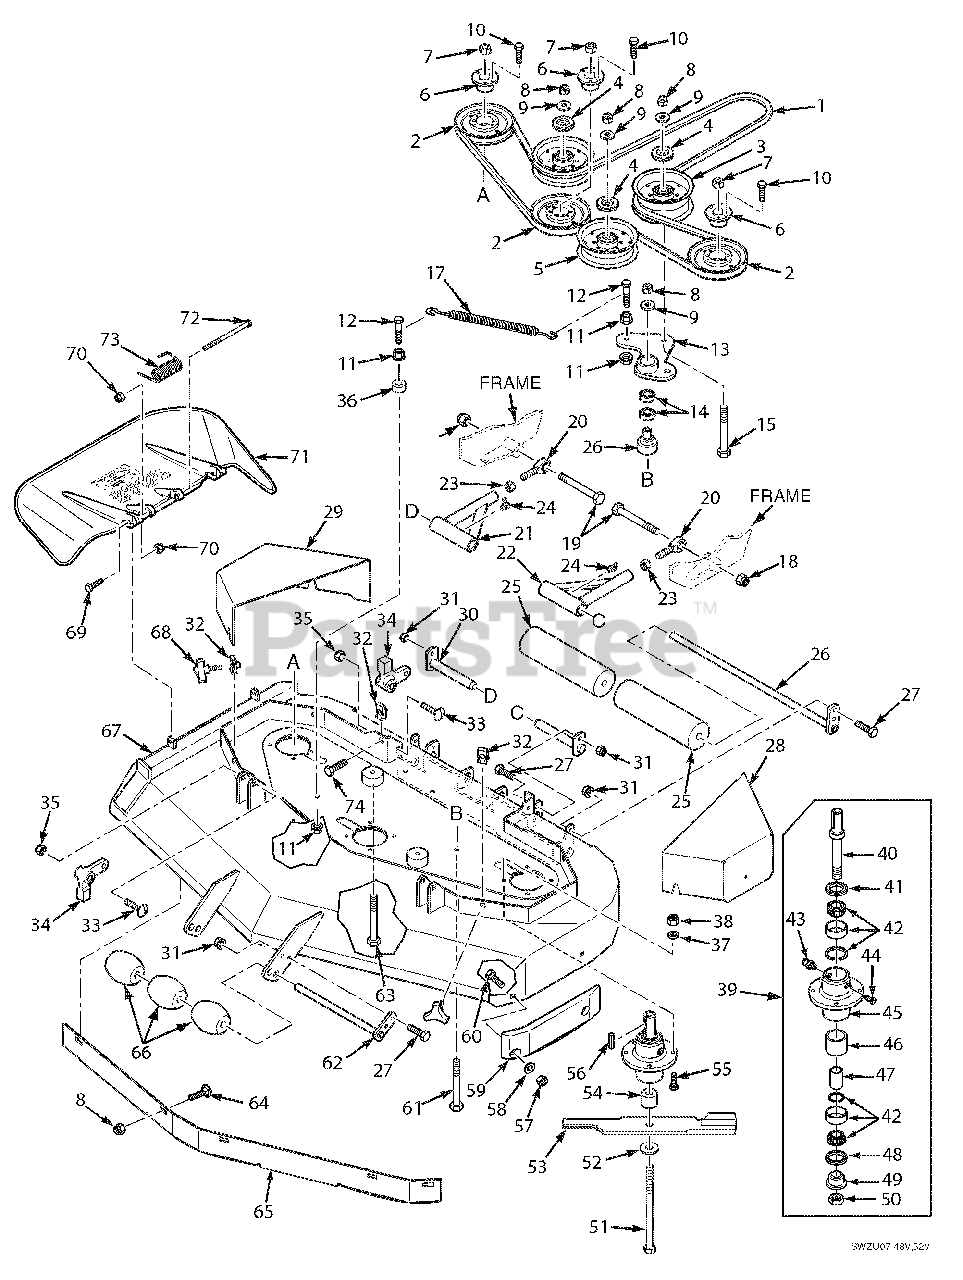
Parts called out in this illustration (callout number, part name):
1	Cutter Deck Belt, SWZV 52V
2	Pulley, 5.75 O.D.
3	Pulley, 5" Idler
4	Dust Shield
5	Pulley, 5" Idler
6	Tapered Hub, 1.125 Bore
7	Nut, 5/8-11 UNC
8	Nut, Elastic Stop 3/8-16
9	Flatwasher, 3/8-.391 x .938 x .105 HD
10	Bolt, Heax Head 1/4-20 x 1" Grade 8
11	N ut, Serrated Flange 3/8-16
12	Bolt, Hex Head 3/8-16 x 1-1/2" Grade 8
13	Idler Arm Assembly
14	Bearing
15	Bolt, Hex Head 3/8-16 x 3"
16	Pivot, Idler
17	Deck Spring
18	Nut, Elastic Stop 1/2-13
19	Bolt, Hex Head 1/2-13 x 3"
20	Rod End, Male 1/2-20 RH Thread
21	Push Arm, RH
22	Push Arm, LH
23	Nut, Jam 1/2-20
24	Grease Fitting, 90 Degree
25	Guide Roller
26	Shaft Weldment
27	Bolt, Hex Head 5/16-18 x 1"
28	Belt Cover, LH
29	Belt Cover, RH
30	Push Arm Shaft
31	Nut, Serrated Flange 5/16-18
32	U-Nut, 3/8-16
33	Bolt, Carriage 7/16-14 x 2-1/4"
34	Lever, Deck Level
35	Nut, Elastic Stop 7/16-14
36	Spacer
37	Lockwasher, 5/16"
38	Nut, Elastic Stop 5/16-18 Grade 8
39	Spindle Assembly
40	Shaft, Spindle
41	Seal, Upper
42	Bearing Assembly
43	Grease Fitting
44	Relief Fitting, Cutter Spindle
45	Spindle Housing
46	Spacer, Ouside
47	Spacer, Inside
48	Seal, Cutter Spindle Bottom
49	Spindle Bushing
50	Nut, Spindle
51	Bolt, Hex Head 5/8-11 x 9-1/2"
52	Flatwasher, 5/8"
53	Cutter Blade, 18"
54	Spacer, Spindle
55	Bolt, Hex Head 5/16-18 x 1-3/4" Grade 8
56	Key, 1/4 x 1/4 x 2"
57	Nut, Center Lock 5/16-18
58	Flatwasher, 5/16"
59	Pad, Deck Wear
60	Bolt, Carriage 5/16-18 x 3/4"
61	Bolt, Hex Head 3/8-16 x 3-1/4"
62	Shaft Weldment
63	Bolt, Hex Head 3/8-16 x 3-3/4"
64	Bolt, Carriage 3/8-16 x 1"
65	Baffle, 52V
66	Wheel, Anti-Scalp
67	Cutter Deck Weldment w/Decals, 52V
68	Knob w/Stud
69	Bolt, Hex Head 5/16-18 x 1-3/4"
70	Nut, Elastic Stop 5/16-18
71	Discharge Chute - 52V
72	Bolt, Hex Head 5/16-18 x 4-1/4"
73	Spring, Discharge Chute
74	Bolt, Hex Head 3/8-16 x 1-1/4" Special Lock
